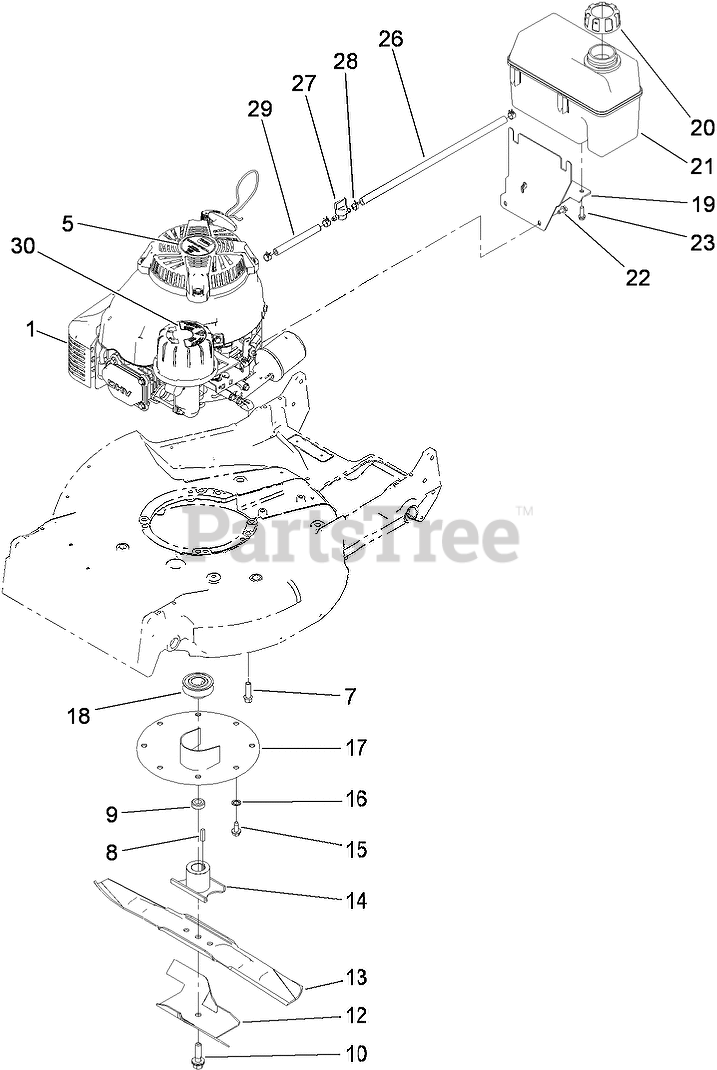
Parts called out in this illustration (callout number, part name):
1	ENGINE-KAWASAKI, FJ180V-BM08-M
7	SCREW-TAPTITE
8	KEY-SQUARE
9	Spacer-Retainer, Blade
10	BOLT-BLADE
12	STIFFENER-BLADE
13	BLADE-21 INCH
14	RETAINER-BLADE
15	SCREW-HWHTF
16	WASHER-LOCK, INTERNAL
17	CRANKSHAFT PROTECTOR ASM
18	PULLEY-DRIVER
19	MOUNT-TANK
20	CAP-GAS
21	TANK-FUEL
22	SCREW-HWH
23	SCREW-HWH
26	HOSE-FUEL
27	VALVE-FUEL
28	CLAMP-HOSE
29	HOSE-FUEL
